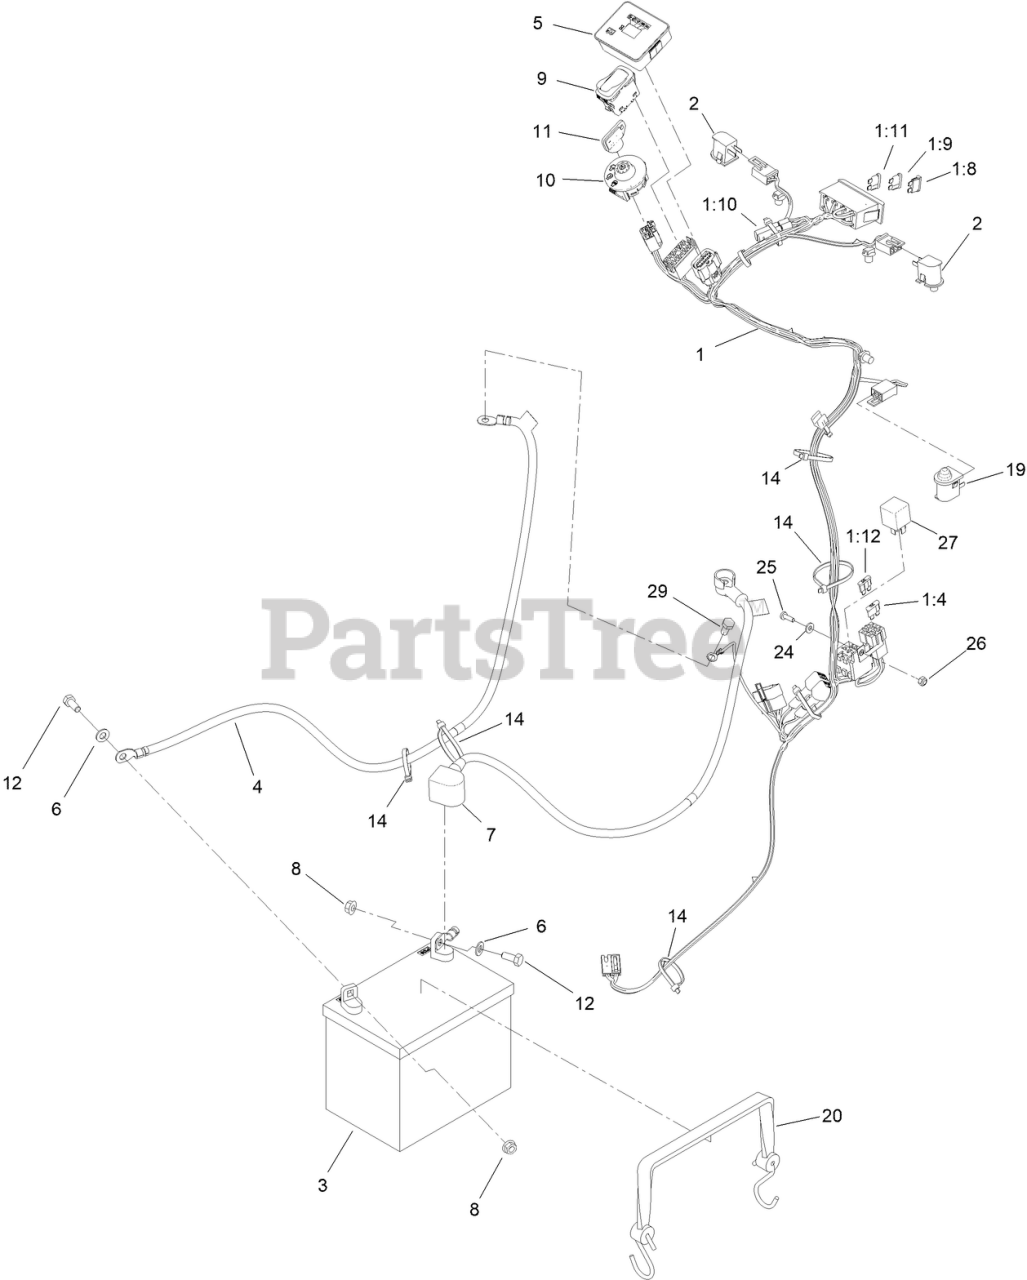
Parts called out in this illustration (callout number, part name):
1	HARNESS-WIRE, GRANDSTAND
1:4	FUSE-BLADE, 20 AMP
1:8	FUSE-BLADE, 15 AMP
1:9	FUSE-BLADE, 10 AMP
1:10	CAP-PLUG
1:11	FUSE-BLADE, 5 AMP
1:12	FUSE-BLADE, 30 AMP
2	SWITCH-BAIL
3	BATTERY-DRY
4	BATTERY-CABLE, BK ASM
5	MODULE-METER, HOUR
6	WASHER-PLAIN
7	BATTERY-CABLE, RD ASM
8	NUT-HHF, SMOOTH
9	SWITCH-ROCKER, (ON)-ON-OFF
10	SWITCH-IGNITION
11	KEY-IGNITION
12	SCREW-HH
14	TIE-CABLE
19	SWITCH-PLUNGER
20	STRAP-RUBBER
24	WASHER-FLAT
25	SCREW-PPH
26	NUT-LOCK, NI
29	SCREW-HH
